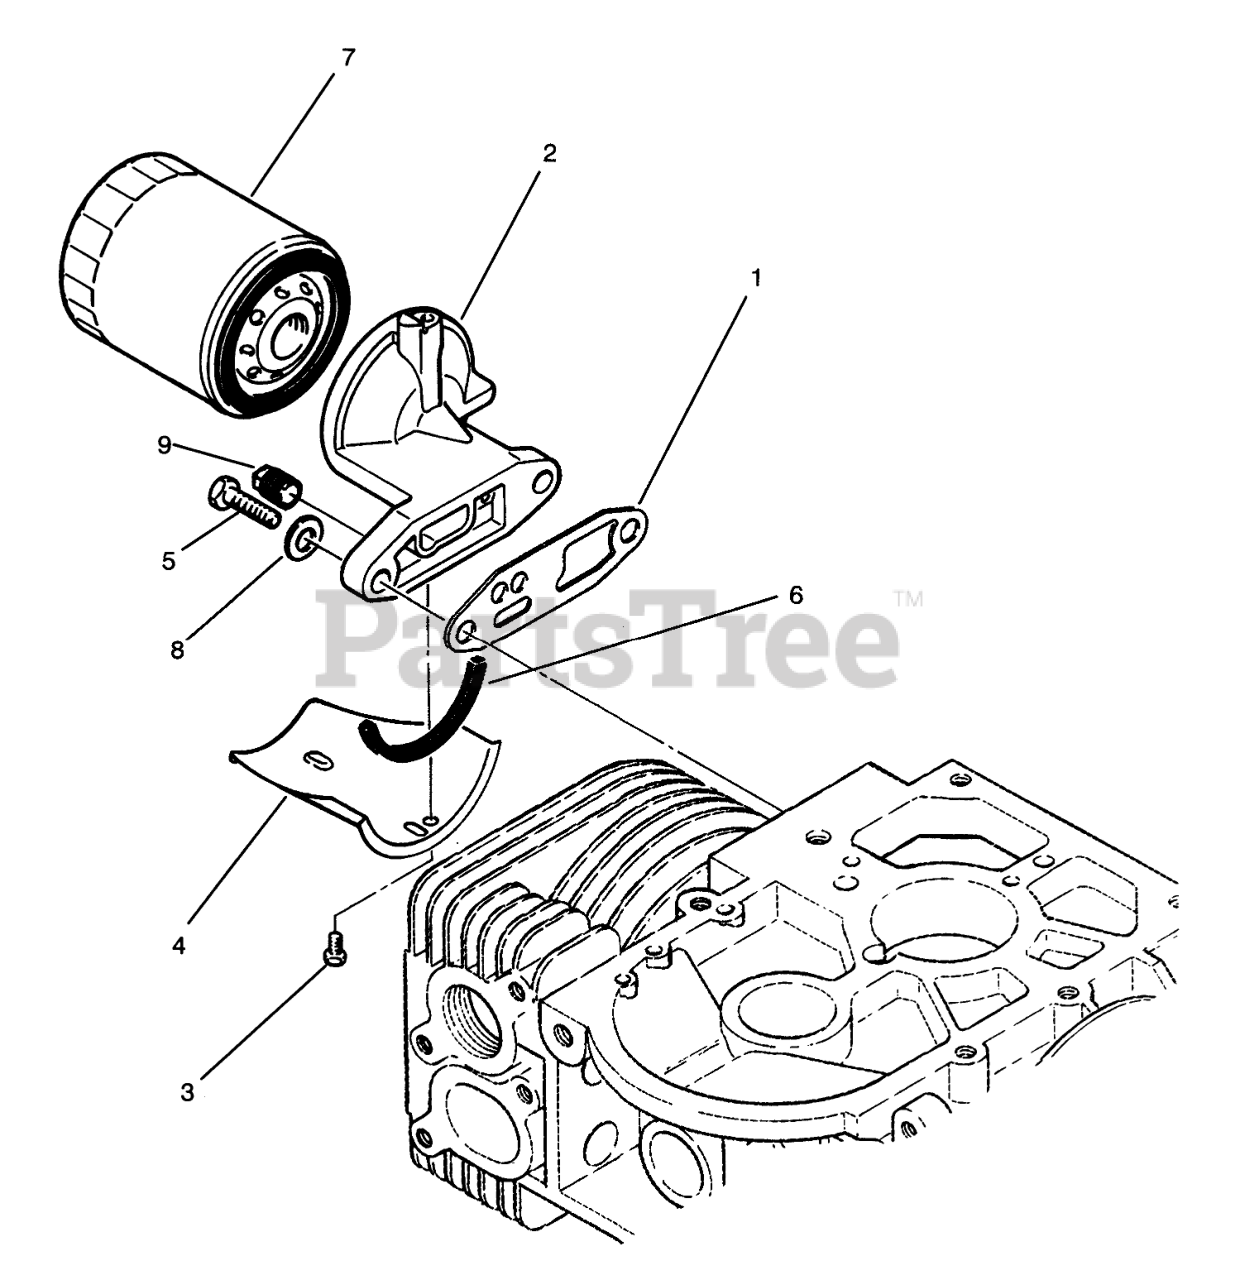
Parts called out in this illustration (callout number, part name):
1	Gasket
2	Adapter
3	Bolt
4	OIL-DRAIN
5	HHCS 5/16-18 X 1
6	OIL-DRAIN SEAL
7	OIL FILTER
8	WASHER
9	Plug
